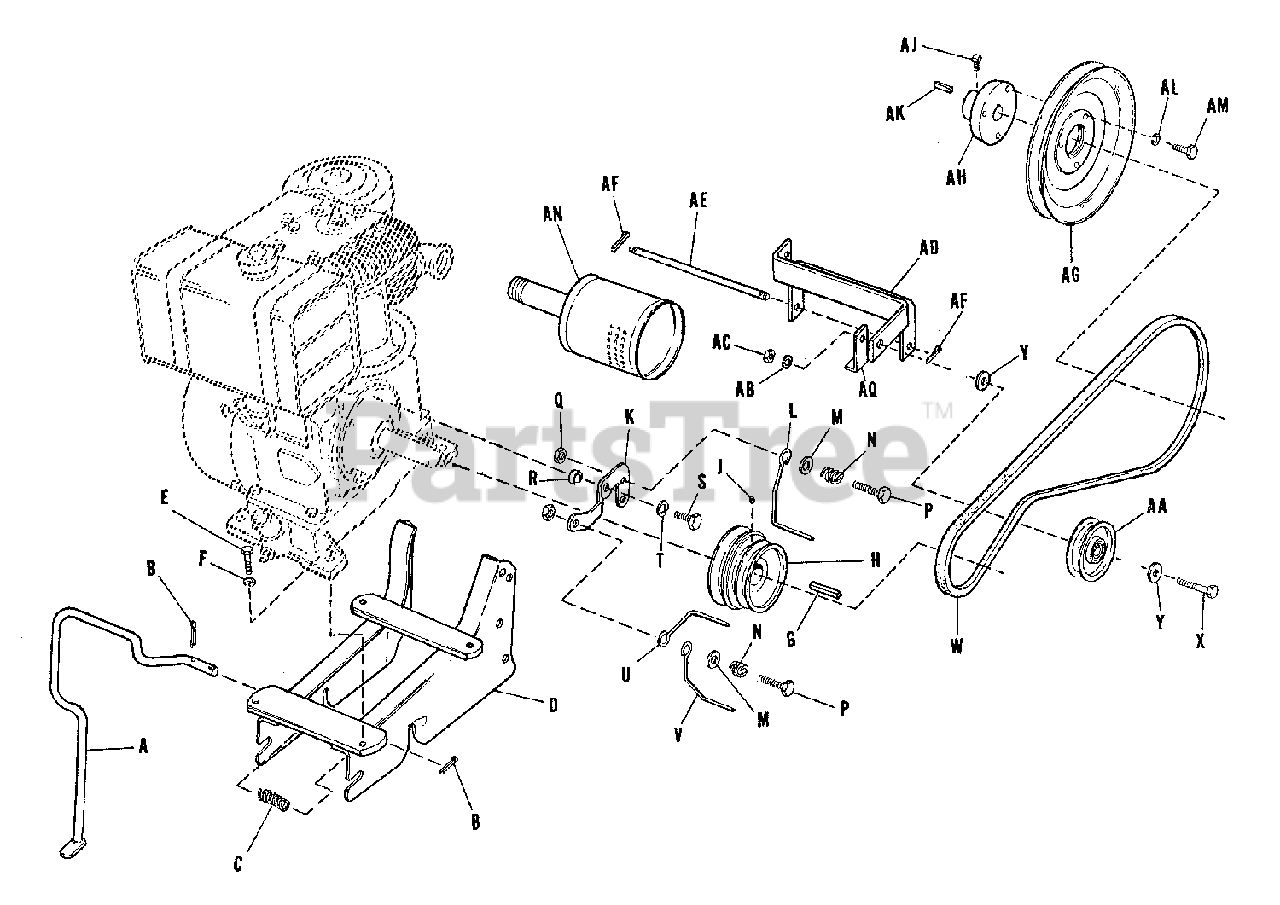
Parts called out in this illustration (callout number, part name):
A	STAND ASSEMBLY
B	PIN, Cotter, 1/8" Diameter x 1" LG
C	SPRING, Stand
D	BASE ASSEMBLY, Engine
E	CAPSCREW, Hex Head, 3/8"-16 NC x 1-1/4" LG
F	WASHER, Lock, 3/8"
H	PULLEY, Engine
J	SCREW, Set, Cup Point, 5/16"-18 NC x 5/16" LG
K	HOLDER, Belt Stop
L	STOP, Belt
M	WASHER, Plain, 5/16"
P	CAPSCREW, Hex Head, 5/16"-18 NC x 1-1/4" LG
Q	NUT, Hex, Jam, 5/16"-18 NC
S	CAPSCREW, Hex, Head, 5/16"-18 NC x 1" LG
T	WASHER, Lock, 5/16"
U	STOP, Belt
V	STOP, Belt
W	BELT, "V" 48"
X	CAPSCRW, Hex Head, 3/8"-16 NC x 1-3/4" LG
Y	WASHER, Plain, 5/16"
AA	PULLEY, Idler
AB	WASHER, Lock, 3/8"
AC	NUT, Hex, Full, 3/8"-16 NC
AD	PIVOT ASSEMBLY, idler
AE	ROD, Pivot
AF	PIN, Cotter, 3/32" Diamerter x 7/8" LG
AG	PULLEY, Transmission 8"
AH	HUB, Pulley
AJ	SCREW, Set, Square head, 5/16-18 NC x 3/8" LG
AK	KEY, Transmission Pulley
AL	WASHER, Lock, 5/16"
AM	CAPSCREW, Hex Head, 5/16"-18 NC x 7/8" LG
AN	MUFFLER, Exhaust
